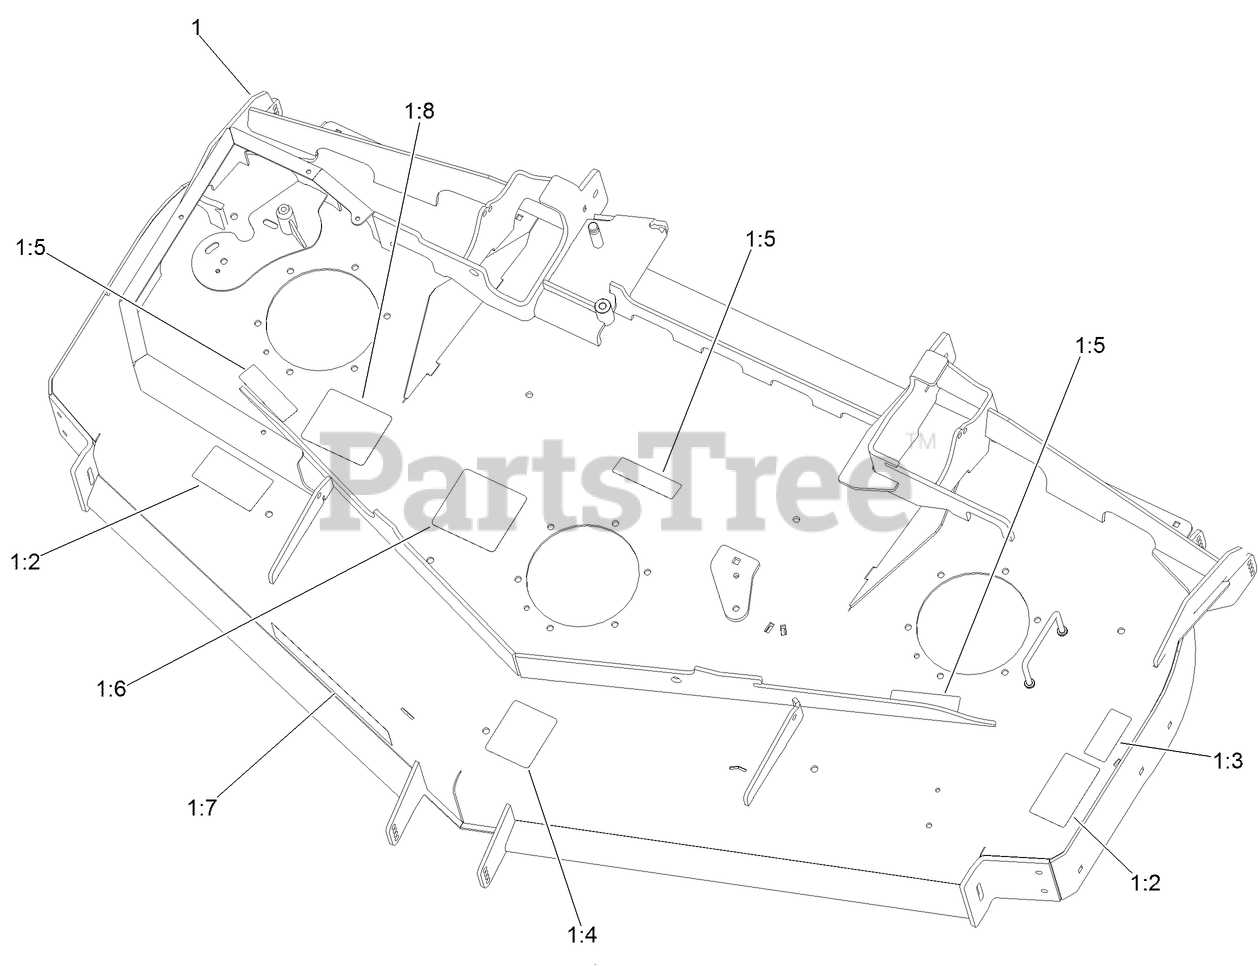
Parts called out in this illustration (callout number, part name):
1	DECK DECAL ASM
1:2	DECAL-DANGER
1:3	DECAL-BOLT TORQUE
1:4	DECAL-ROLLER, ANTI-SCALP
1:5	DECAL-COVER, MISSING
1:6	DECAL-ROUTING, DECK BELT
1:8	DECAL-SPINDLE CR, CE
